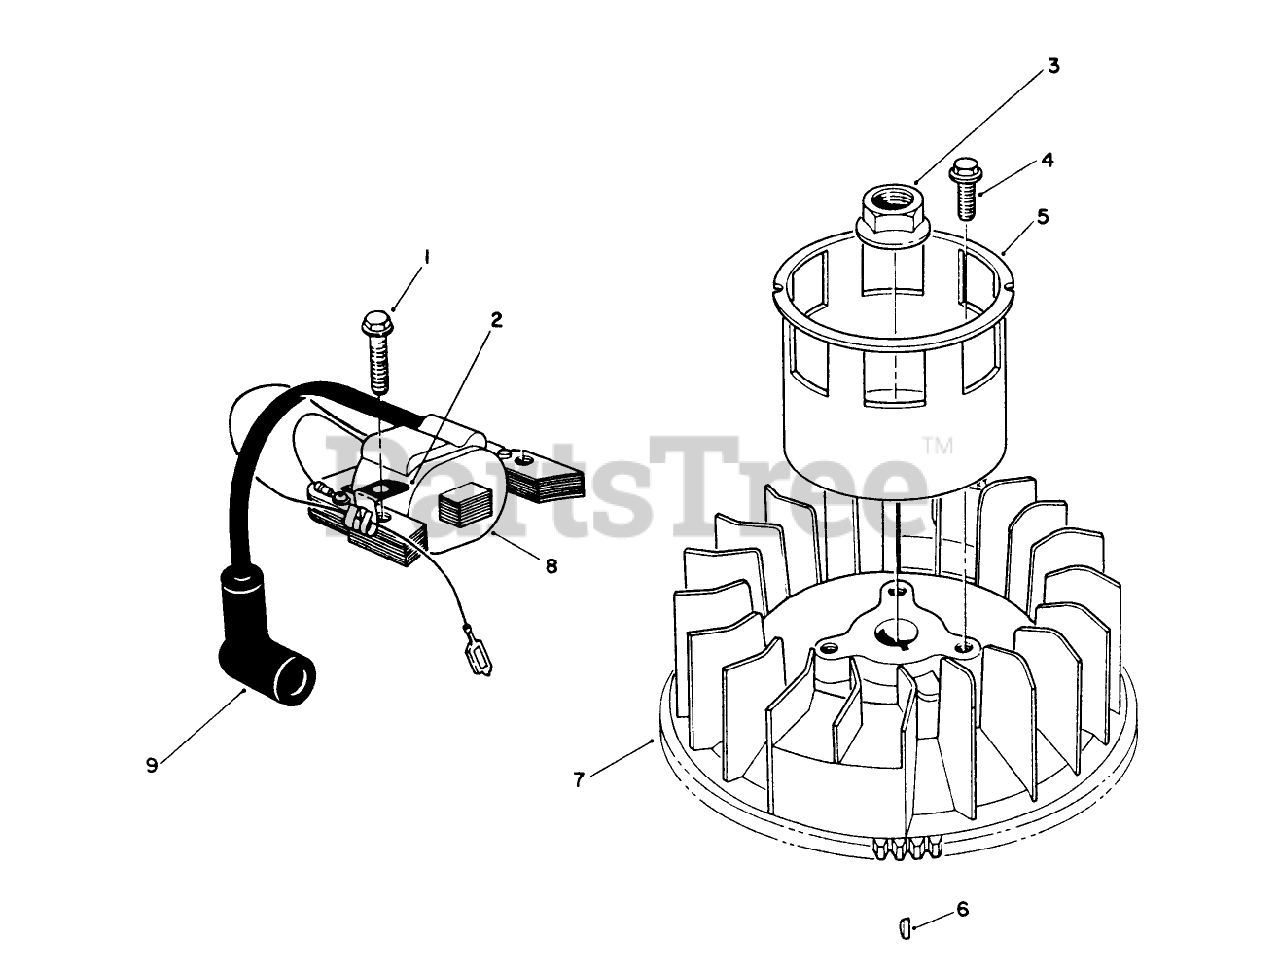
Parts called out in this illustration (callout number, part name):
2	CLAMP
7	FLYWHEEL
8	COIL ASM
9	COVER
